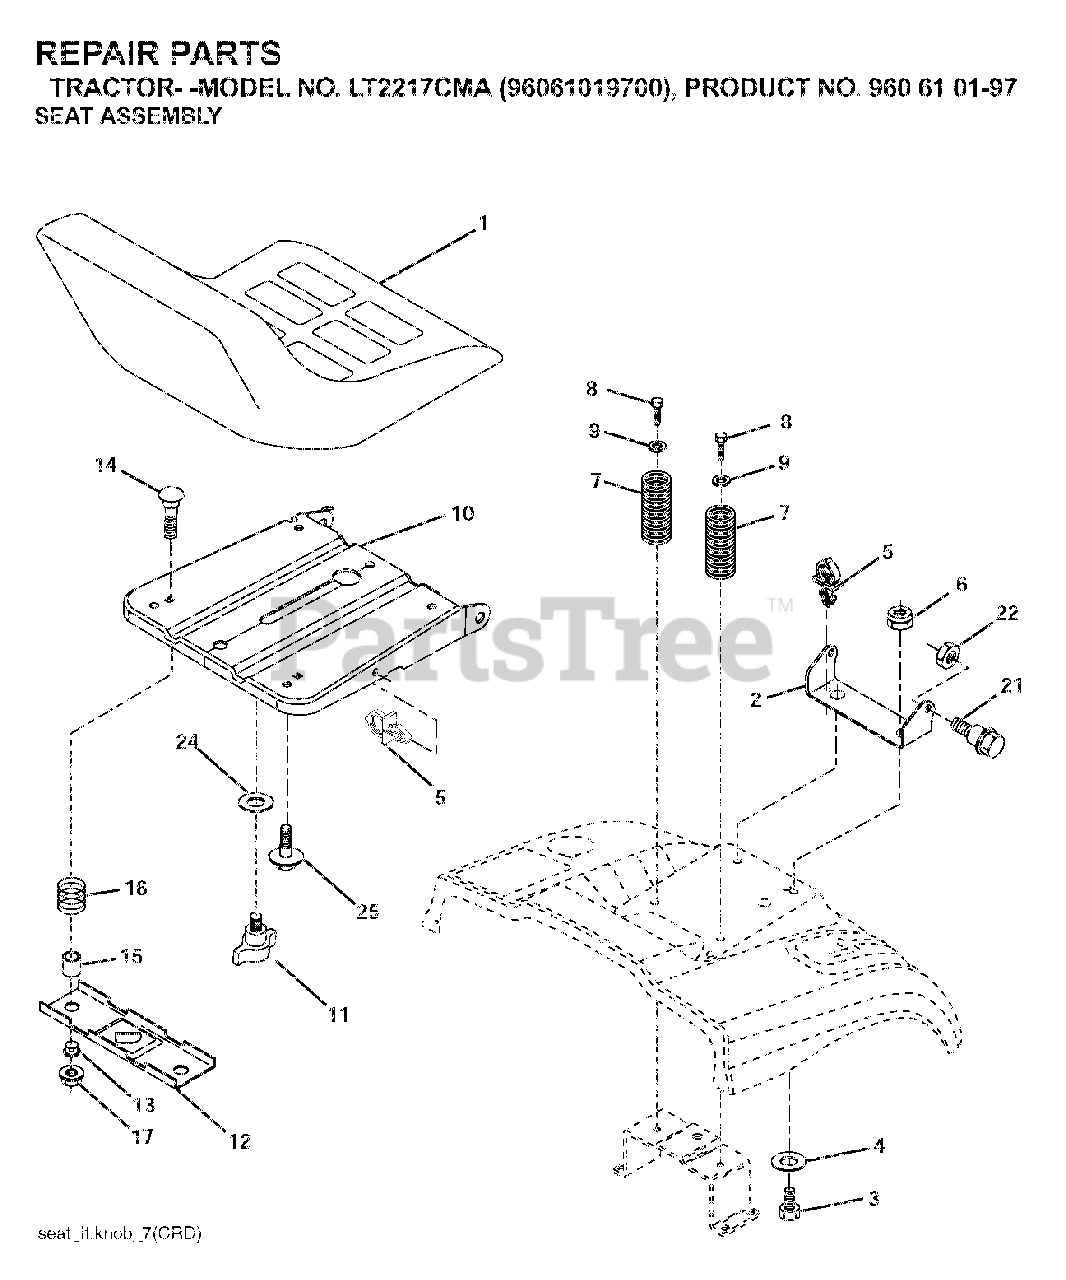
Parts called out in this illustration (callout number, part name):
2	SEAT PIVOT BRKT
4	WASHER PM
5	PUSH CLIP
6	NUT
7	SPRING COMPRESSION
8	SCREW 3/8-16X1
9	WASHER
10	PAN.ASM.SEAT.1SLOT
11	KNOB.SEAT.ADJ.WINGNUT
12	BRKT.MNTNG.SWITCH.SEAT
14	BOLT.ROUND.HEAD.SQUARE.NECK
15	SPACER SPLIT 28X.96
17	NUT T
21	BOLT.SHOULDER.5/16-18
22	NUT.71038.31-18.HEX.NYLOCK
25	BOLT,SHOULD
